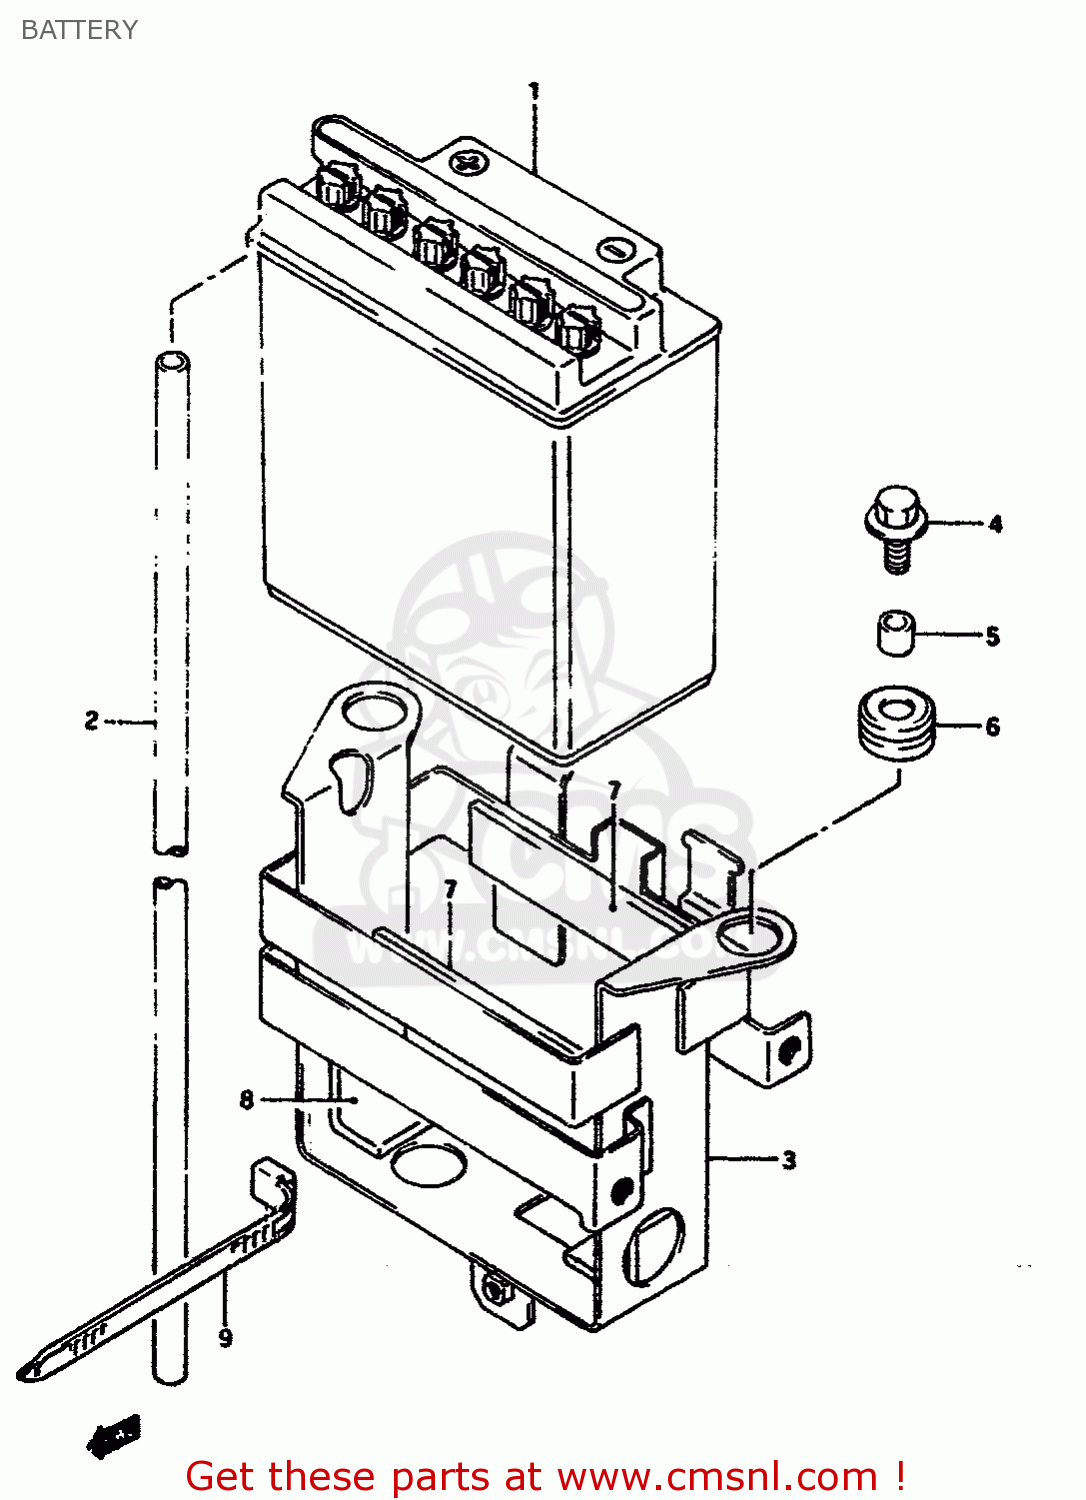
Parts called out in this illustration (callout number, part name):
1	BATTERY ASSEMBLY (12V)
2	HOSE,BATTERY EXHAUST
3	HOLDER,BATTERY
4	BOLT
5	SPACER(6.1X9X7.5)
6	CUSHION
7	PROTECTOR,20X9
8	PROTECTOR(30X80X2)
9	CLAMP(L:125)
